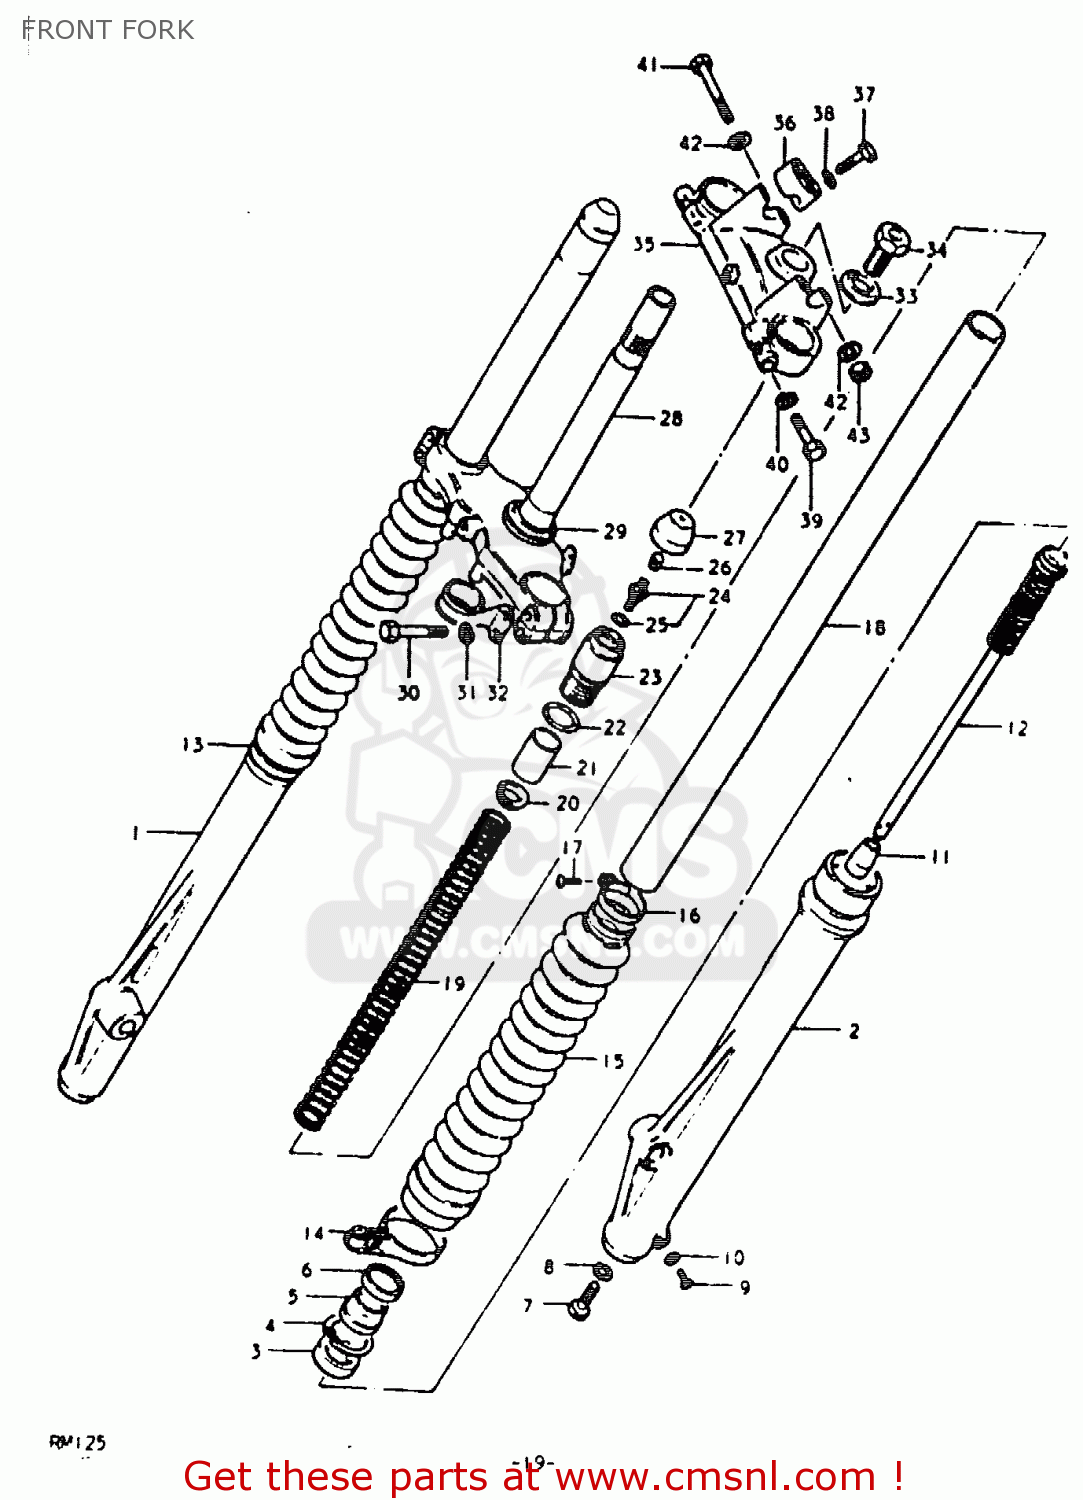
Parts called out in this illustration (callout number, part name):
1	TUBE,OUTER,RIGHT
2	TUBE,OUTER,LEFT
3	CIRCLIP,FORK OIL SEAL
4	CIRCLIP,FORK OIL SEAL
5	DUST SEAL,FRONT FORK
6	CASE,DUST SEAL FRONT FORK
7	BOLT,CYLINDER
8	GASKET,CYLINDER (NAS)
9	SCREW
10	GASKET,DRAIN,PLUG (NAS)
11	PIECE,OIL LOCK
12	CYLINDER
13	BAND,FRONT FORK COVER BOOT
14	BAND,FRONT FORK COVER BOOT
15	BOOT
16	BAND,BOOT
17	SCREW
18	TUBE,FORK,INNER
19	SPRING
20	GUIDE
21	COLLAR,SPRING
22	O RING
23	CAP,FORK INNER TUBE
24	VALVE
25	O RING
26	CAP,VALVE AIR
27	CAP
28	STEM,STEERING
29	RACE,STEERING,OUTER,UPPER
30	BOLT 8X45
31	LOCK WASHER
32	GUIDE,CABLE
33	WASHER
34	BOLT
35	HEAD,STEERING STEM
36	HOLDER,HANDLEBAR
37	BOLT
38	LOCK WASHER
39	BOLT
40	LOCK WASHER
41	BOLT 8X50
42	WASHER
43	NUT
